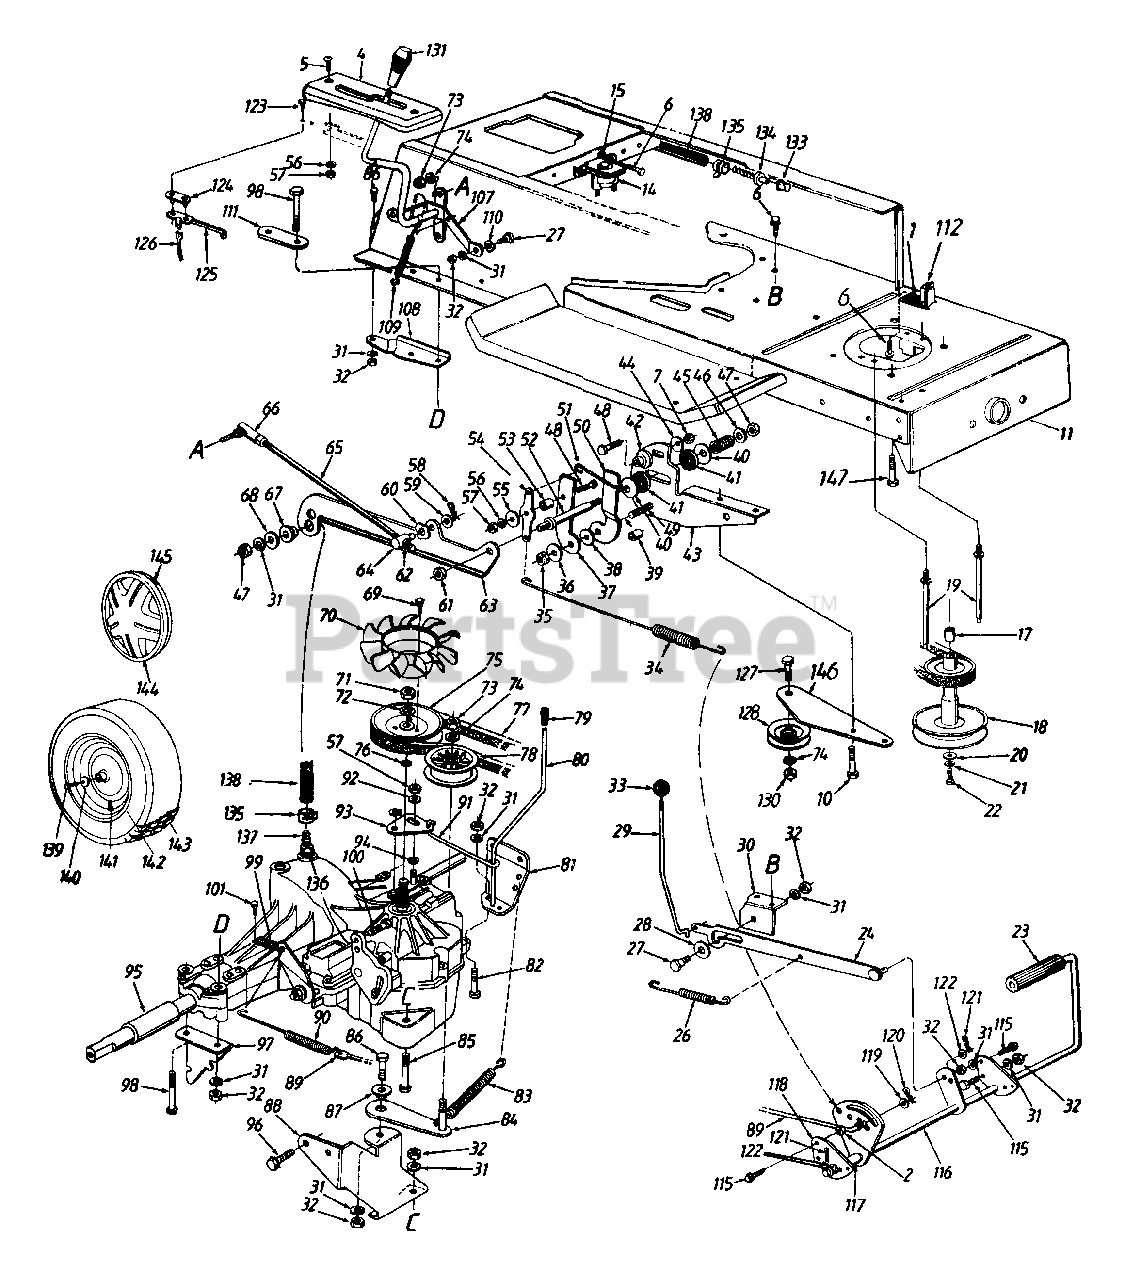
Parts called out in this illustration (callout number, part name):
1	Spring Switch
2	Hex Sems Nut 5/16-18 Thd.
4	Index Bracket
5	Pan Hd. Mach. Scr. 1/4-20 x .75" Lg.
6	Hex Wash. Hd. TT-Tap Scr. 1/4-20 x .5" Lg.
7	Hex Nut 1/4-28 Thd.
10	Hex Bolt 1/4-28 x .62" Lg.
14	Solenoid
15	Ext. L-Wash. 1/4" I.D.
18	Engine Pulley
19	Belt Guard Stud 4.75" Lg.
20	Fl-Wash. 7/16" I.D. x 1.25" O.D.
21	L-Wash. 7/16" I.D.
22	Hex Bolt 7/16-20 x 1.5" Lg.
23	Foot Pad
27	Shld. Bolt .437" Dia. x .268"
28	Fl-Wash. 7/16" I.D. x 1-3/8" O.D.
29	Lock-up Rod
31	L-Wash. 5/16" I.D.
32	Hex Nut 5/16-18 Thd.
34	Neutral Return Spring
35	Hex Nut 5/16-24 Thd.
36	Fl-Wash. .344" I.D. x 1" O.D.
37	Scissor-Flat
38	Fl-Wash. .33" I.D. x 1.25" O.D.
40	Bell-Wash. .4" I.D. x 1.13" O.D.
41	Friction Washer
42	Centering Gauge Spacer
43	Neutral Return Mtg. Brkt.
44	Bell-Wash. .265" I.D. x .75" O.D.
45	Comp. Spring 1.19" Lg.
46	Fl-Wash. .26" I.D. x .72" O.D.
47	Hex Nut 5/16-24 Thd.
48	Hex Bolt 1/4-28 x 1" Lg. (Gr. 5)
49	Rib Neck Bolt 5/16-24 x .84" Lg.
50	Scissor-Offset
51	Neutral Return Rod
52	Friction Disc Stud
53	Shld. Spacer
54	Neutral Return Lever
55	Fl-Wash. .265" I.D. x 1" O.D.
56	L-Wash. 1/4" I.D.
57	Hex Nut 1/4-20 Thd.
58	Hairpin Clip
59	Fl-Wash. .375" I.D. x .87" O.D.
60	Spring Wash. .39" I.D.
61	Hex L-Nut 3/8-24 Thd.
62	Hex Jam Nut 3/8-24 Thd.
63	Neutral Return Brkt.
64	Ferrule 3/8-24 Thd.
65	Control Rod
66	Ball Joint 3/8-24 Thd.
67	Shld. Spacer .5" Dia. x .27" Lg.
68	Fl-Wash. .349" I.D. x .879" O.D.
69	Hex Wash. Hd. Tap Scr. #12 x 3/8" Lg.
70	Fan
71	Hex Nut 1/2-20 Thd.
72	L-Wash. 1/2" I.D.
73	Hex Nut 3/8-24 Thd.
74	L-Wash. 3/8" I.D.
75	Transmission Pulley
77	"V"-Belt
78	Fl-Idler Pulley 2.75" O.D.
79	Rod End Grip
80	Bypass Control Lever
83	Ext. Spring 6.12
86	Hex Bolt 5/16-18 x .75" Lg.
87	Shld. Spacer .5" Dia. x .27" Lg.
90	Ext. Spring
91	Bypass Actuator Rod
92	Fl-Wash. .281" I.D. x .5" O.D.
93	Bypass Adjustment Brkt.
94	External L-Wash. 1/4" I.D.
95	Sleeve .758" I.D. x 1" O.D.
96	Hex . Wash. TT-Tap Scr. 5/16-18 x .62" Lg.
99	Tension Spring
100	Hex Bolt 5/16-24 x 1" Lg. (Special)
101	Hex Wash. Hd. AB-Tap Scr. #10 x .5" Lg.
107	Speed Control Lever Ass'y.
110	Spr-Wash. .445" I.D. x .75" O.D.
112	Safety Switch (Clutch)
115	Hex Wash. TT-Tap Scr. 5/16-18 x .75" Lg.
120	Cotter Pin 3/32" Dia.
121	Cotter Pin 1/8" Dia.
122	Fl-Wash. .385" I.D. x .62" O.D.
123	Hex Wash. Hd. AB-Tap Scr. #8 x .5" Lg.
124	Insulator Nut Plate
125	Reverse Safety Switch
126	Extension Wire
127	Hex Bolt 3/8-16 x 1.5" Lg.
128	Idler Pulley
130	Hex Nut 3/8-16 Thd.
134	Plastic Vent
135	Clamp
137	Hose Fitting
138	Fuel Line 18" Lg.
139	Hex Bolt 5/16-24 x .75" Lg.
140	Bell-Wash. .345" I.D. x .88" O.D.
141	Air Valve
144	Hub Cap (LT-155)
145	Spring Clip (LT-155)
